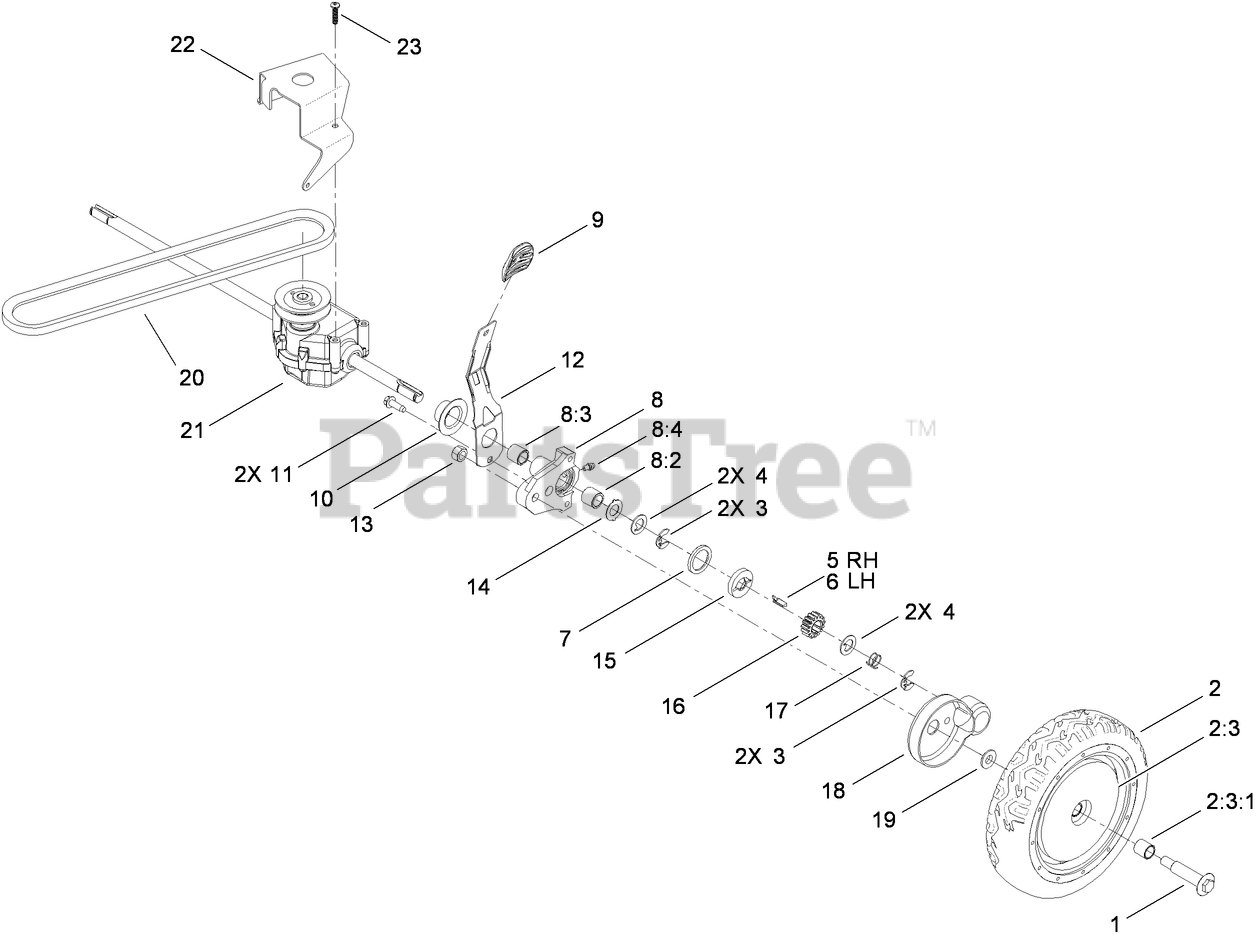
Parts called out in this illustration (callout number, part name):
1	BOLT-SHOULDER
2	WHEEL GEAR ASM
2:3	Loose Parts Package
2:3:1	BUSHING
3	RING-RETAINING,CLIP
4	WASHER-THRUST, KEYED
6	KEY-ROCKING, LH
7	RING-FRICTION
8	PIVOT ARM ASM
8:2	BUSHING
8:3	BUSHING
8:4	FITTING-GREASE
9	KNOB-LEVER, HOC
10	CAP-END
11	SCREW-HWHTF
12	ARM-SPRING
13	LOCKNUT
14	WASHER-ARM, PIVOT
15	WASHER-CLUTCH
16	GEAR-PINION
17	SPRING-COMPRESSION
18	COVER-WHEEL
19	SPACER-COVER, WHEEL
20	V-BELT
22	BRACKET-TRANSMISSION
23	SCREW-PLASTITE
